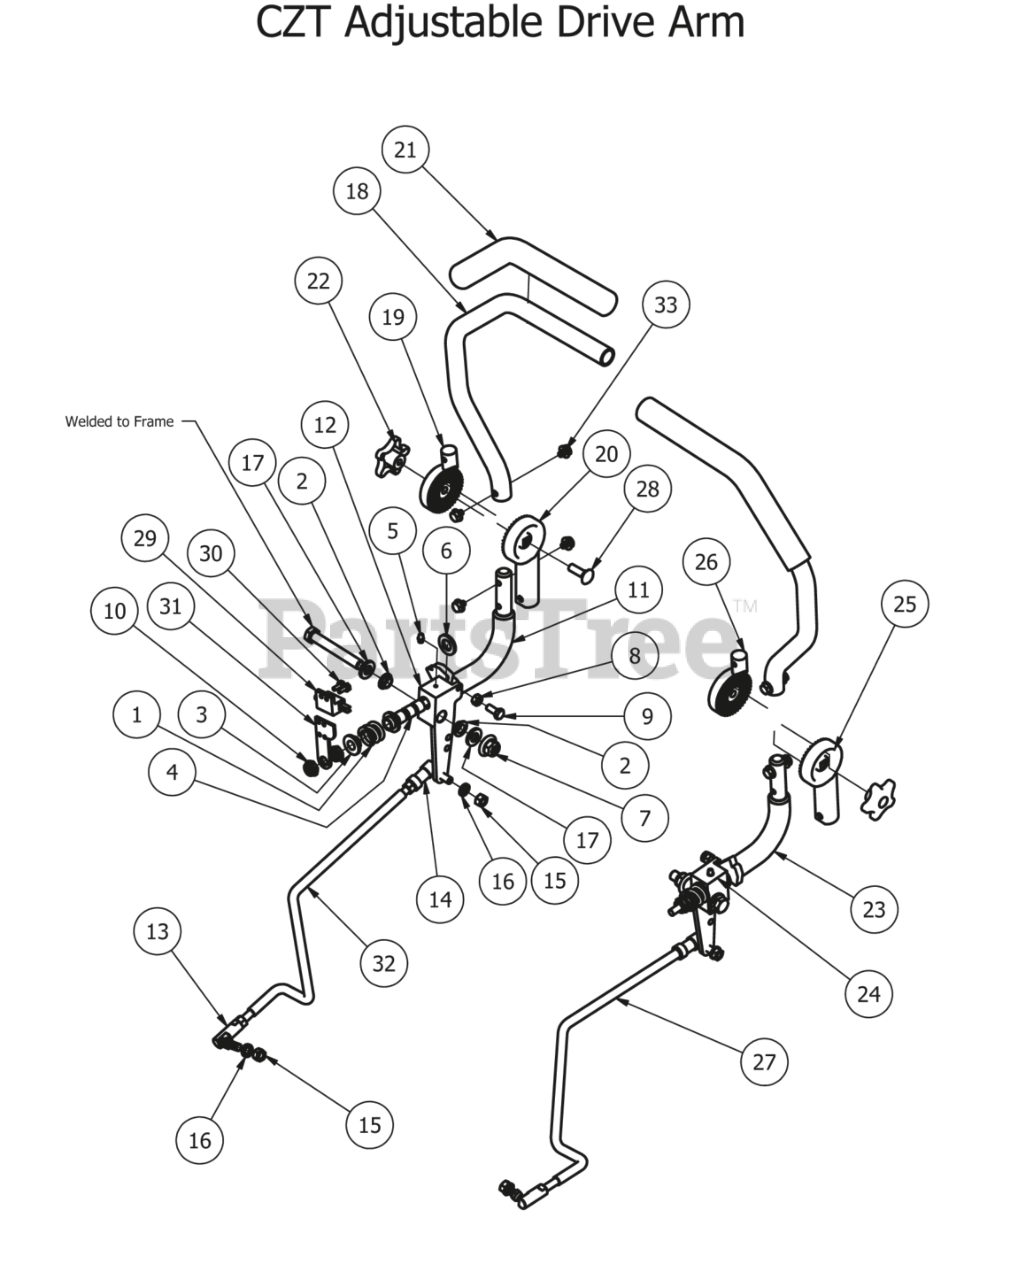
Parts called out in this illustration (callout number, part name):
1	Drive Lever Spring
2	Bushing for 2012 Drive Arms
3	.515 ID Nylon Shoulder Washer
4	.507 ID Nylon Bushing
5	1/4" Drive in Grease Fitting
6	.635 ID Plastic Washer
7	1/2-13 Nylon Flange Nut-Orange
9	5/16" x 3/4" Hex Bolt
10	1/2" Nylcock Nut (1/2 Jam)
11	Steering Arm Elbow - Left
12	Drive Arm Lever Housing (Left)
13	3/8-24 Ball Joint
14	3/8-24 Quick Release Ball Joint
15	3/8" Fine Threaded Jam Nut
16	3/8" Lock Washer
17	.505x1x.125 Oil Impregnated washer
18	Upper Tube-Adjustable Steering
19	Upper adjuster-Steering Arm- Left
20	Lower Adjuster - Steering Arm- Left
21	Rubber Grip
22	Black Knob for Adjustable Steering Arm
23	Steering Arm Elbow - Right
24	Drive Arm Lever Housing (Right)
25	Lower Adjuster - Steering Arm- Right
26	Upper Adjust Steering Arm- Right
27	Transaxle Drive Rod (Right)
28	3/8" x 1 1/4" Carriage Bolt
29	Safety Switch
30	12-24x 1/2 HWH Bolt
31	Switch Bracket-ZT
32	Transaxle Drive Rod (Left)
33	5/16-18 1/2 HWH Bolt-Steering
